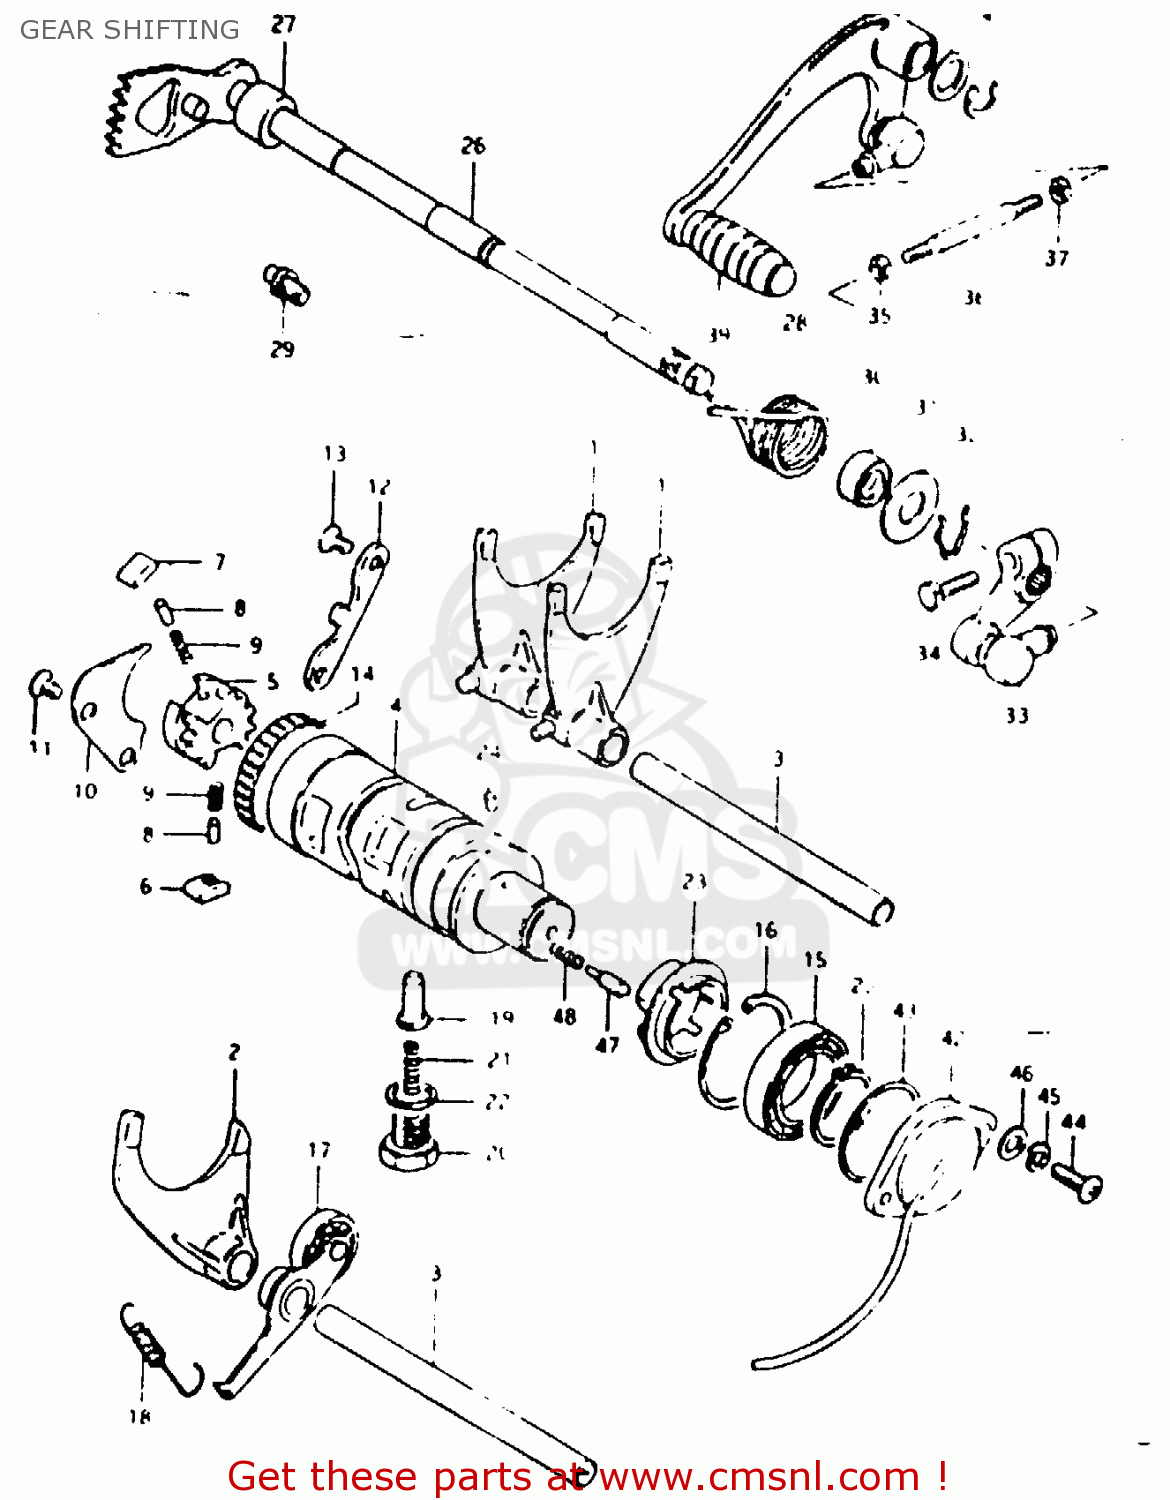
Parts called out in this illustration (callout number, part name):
1	FORK,GEAR SHIFT NO.1
2	FORK,GEAR SHIFT NO.2
3	SHAFT,GEAR SHIFT FORK
4	CAM,GEAR SHIFT
5	RETAINER,GEAR SHIFT CAM
6	PAWL,GEAR SHIFT NO.1
7	PAWL,GEAR SHIFT NO.2
8	PIN(5X8)
9	SPRING
10	LIFTER,GEAR SHIFT PAWL
11	SCREW
12	GUIDE,GEAR SHIFT CAM
13	SCREW
14	BEARING(43X49X12)
15	BALL BEARING
16	CIRCLIP,42MM
17	STOPPER,GEAR SHIFTING
18	SPRING
19	STOPPER,GEAR SHIFT CAM NO.2
20	HOLDER,GEAR SHIFT CAM STOP SPR
21	SPRING
22	GASKET(14X19.2X2) (NAS)
23	PLATE,GEAR SHIFT CAM STOPPER
24	PIN 4X6
25	CIRCLIP
26	SHAFT,GEAR SHIFT
27	SPACER(12X20X15.3)
28	SPRING
29	STOPPER,GEAR SHIFT CAM
30	OIL SEAL
31	WASHER (12.5X27X1.6)
32	SPRING,RETAINER
33	ARM,GEAR SHIFT LINK
34	BOLT
35	NUT
36	ROD,GEAR SHIFT LINK
37	NUT
38	LEVER ASSY,GEA
39	RUBBER,PEDAL
40	WASHER(12.5X20X1)
41	CIRCLIP
42	BODY, SHIFTING SWITCH
43	O RING(D:2.4,ID:36.5)
44	SCREW
45	LOCK WASHER
46	WASHER
47	PIN(5X15.5)
48	SPRING
